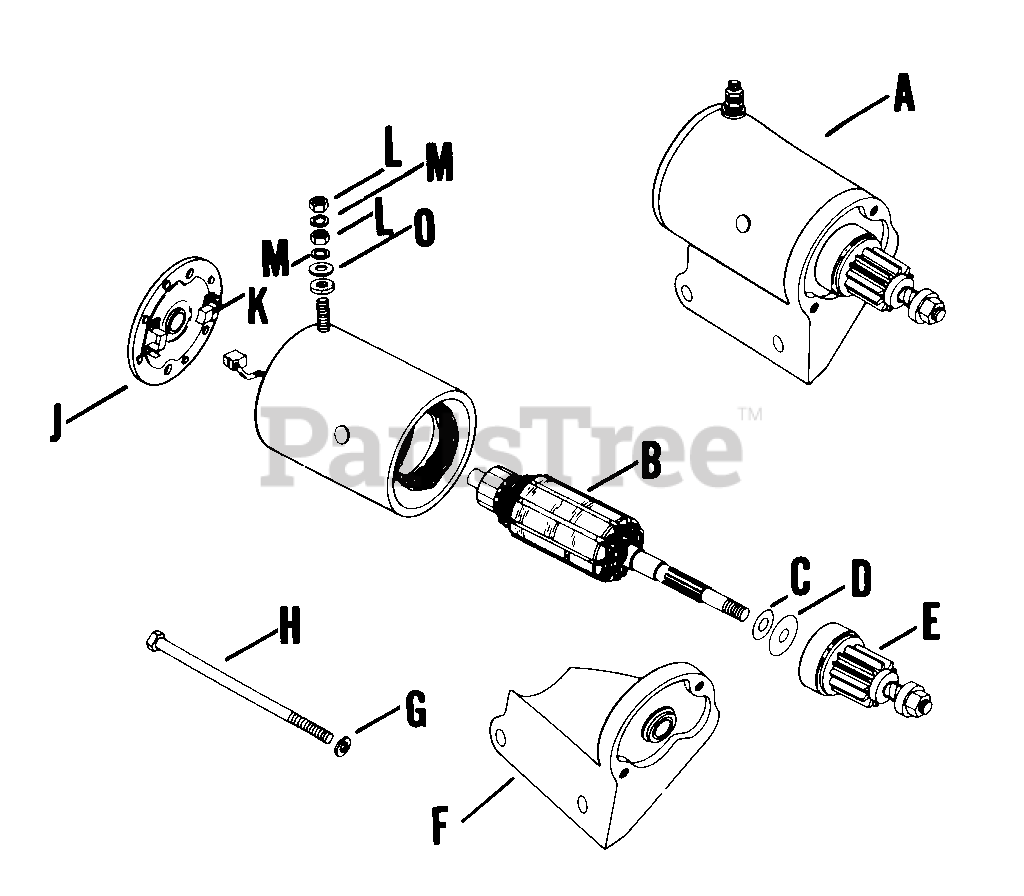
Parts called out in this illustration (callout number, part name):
A	KIT, STARTER - DISCONTINUED
B	ARMATURE - DISCONTINUED
E	DRIVE - DISCONTINUED
G	KIT - USE 237761
H	BOLT - DISCONTINUED
K	KIT - DISCONTINUED
L	KIT - USE 237761
